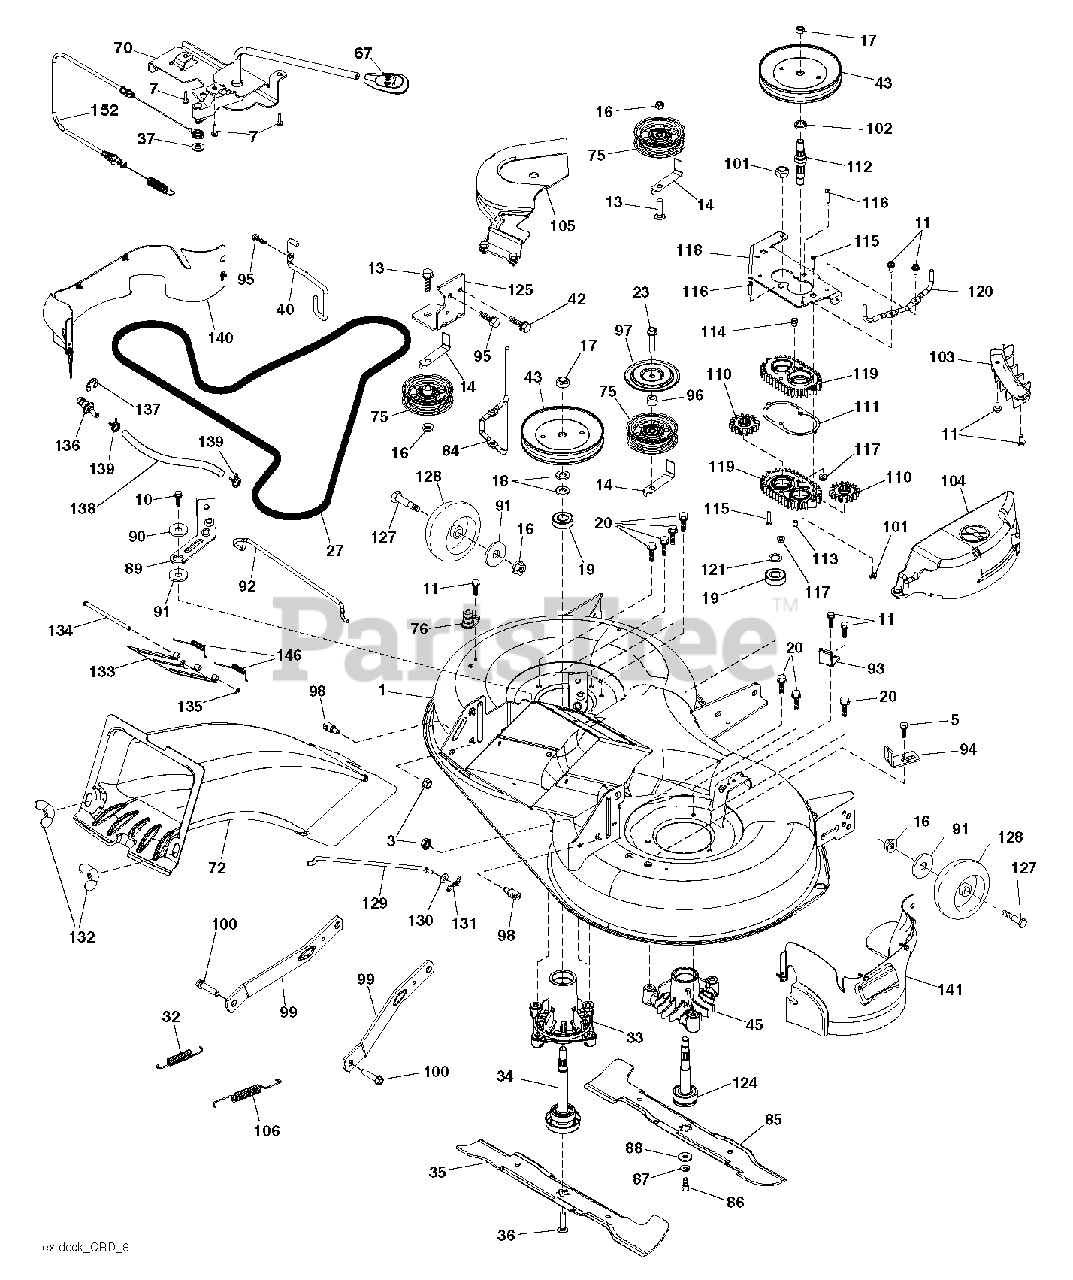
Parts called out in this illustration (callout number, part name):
3	NUT LOCK HEX FLANGE 5/16-18
5	BOLT.5/16HEX.WHS.HD
7	SCREW.#10 X 0.750.BOS THREAD
10	SCREW 3/8-16X1
11	SCREW.1/4-20X5/8
13	BOLT.3/8-16X1.50
14	KEEPER, BELT IDLER
16	NUT LOCK FLG 3/8-16 UNC
17	NUT.FLANGE.LOCK.TOP
18	WASHER.SPACER.MANDREL
20	SCREW, WASHER HEAD
23	SCREW LT
27	BELT VBELT DRIVE
32	SPRING RETURN
33	HOUSING MANDREL
34	SHAFT.ASM.MDRL.N/GREASE.38
35	BLADE.3N1.LH.CRD.97
36	BOLT.WASHER.ASM.7/16-2
40	KEEPER BELT ENGINE LH
42	SCREW
43	PULLEY.MANDREL.5.438.PD
45	HOUSING.MANDREL
67	HANDLE.CLUTCH.CABLE.LT
70	CLUTCH.ASM.MANUAL.LT.TEX
72	CHUTE UPPER *SUBS/2*
75	FLAT IDLER PULLEY
76	12 BARB.DECK.WASHOUT.
84	KEEPER.BELT.MANDREL.PULLEY
85	BLADE.3N1.RH.CRD.97
86	BOLT.3/8-24X1.25GR8. LHTHRD
87	LOCKWASHER
89	ARM.BRAKE.97.LH
90	SPACER.RETAINER
92	ROD ROD BRAKE
93	ARM.BRAKE.97.RH
94	BRKT.CLUTCH.CABLE
95	SCREW, 3/8-16X3/4
98	STUD.FASTNER.W/ANTI-ROTATE
99	ARM.SUSPENSION.MOWER.R
100	BOLT.SHOULDER
101	NUT.CROWNLOCK.9/16 -18.UNC
102	SPACER BEARING
103	GUARD GUARD FRONT VEN
106	SPRING.BRAKE.RETURN.38"
110	RP.CRD.GEAR.OUTPUT
111	GASKET GASKET GEARCAS
113	PLUG PLUG OIL
114	VALVE VALVE RELIEF
115	Screw
116	BOLT.CARIGE.SS.1/4-20X1.75GR5
117	NUT T
118	ARM ARM CLUTCHING
119	GEARCASE GEARCASE SUB
120	BRACKET KEEPER BELT R
121	Washer, .687ID X 1OD X 062 THK
124	Mandrel Shaft, Non/Greaseable
125	Bracket
127	BOLT.SHOULDER.3/8-16X3-5/8
128	WHEEL. GUAGE RALLY
129	ROD.ANTI.SWAY.48/54"K4
130	WASHER
131	PIN.COTTER.5/16.BOW TI
132	KNOB.HANDLE.3/8.TRI-POINT.BLAC
133	DOOR
134	Hinge Pin
136	PLUG WASHOUT PORT HOO
138	HOSE.3/8ID.BULK.12"
139	HOSE.3/8.CLAMP (2 2)
152	CABLE CABLE CLUTCH MA
